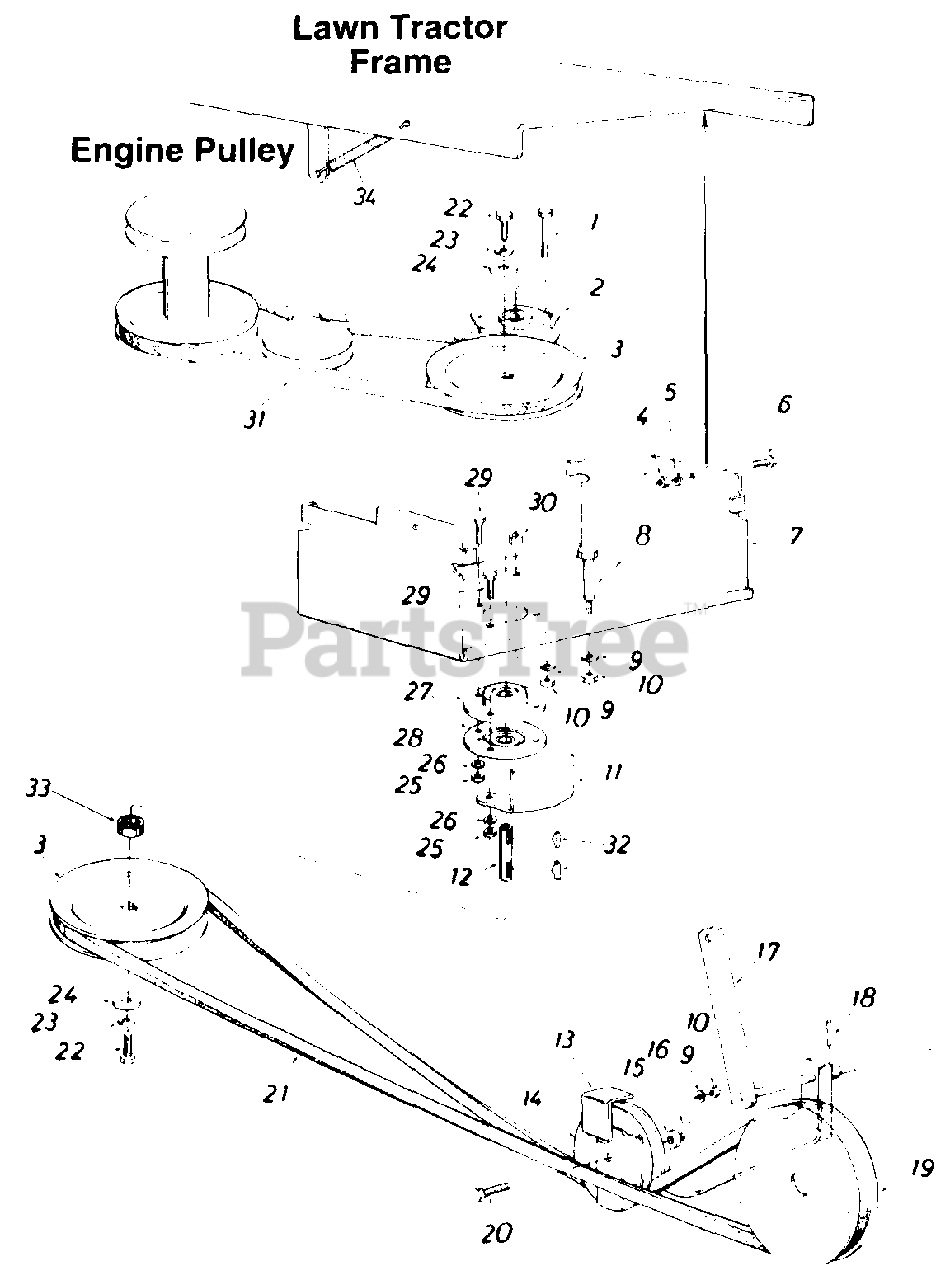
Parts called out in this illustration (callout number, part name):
1	Hex Bolt 3/8-16 x 2" Lg.
2	Fl-Idler w/Flanges 3-3/4" O.D.
3	5/8" "V"-Pulley .79" I.D. x .65" O.D.
4	Hex Nut 3/8-24 Thd.
5	L-Wash. 3/8" I.D.
6	Hex Bolt 3/8-24 x .88" Lg.
9	l-Wash. 3/8" I.D.
10	Hex Nut 3/8-16 Thd.
13	Belt Separator Plate
14	Fl-Idler w/Flanges 3.25"
15	Fl-Wash..406" I.D. x 1.25"
18	Spring Pin Roll 3/16" Dia.
19	5/8" V-Pulley 1.50" I.D. x 6.5" O.D.
20	Hex Bolt 3/8-16 x 1.75" Lg.
21	"V"-Belt
22	Hex Bolt 5/16-18 x .88" Lg. Spec.
23	L-Wash. 5/16" I.D.
24	Fl-Wash..344" I.D. x 1.125"
25	Hex Nut 5/16-18 Thd.
26	L-Wash. 5/16" l.D.
27	Bearing Housing 1.85" I.D.
28	Ball Bearing 1.85" O.D.
29	Hex Sems Bolt 5/16-18 x .75"
30	Spacer
31	Belt
32	Hi-Pro Key 3/16" x 5/8"
33	Spacer.66" I.D. x 1" O.D.
34	Extension Spring
